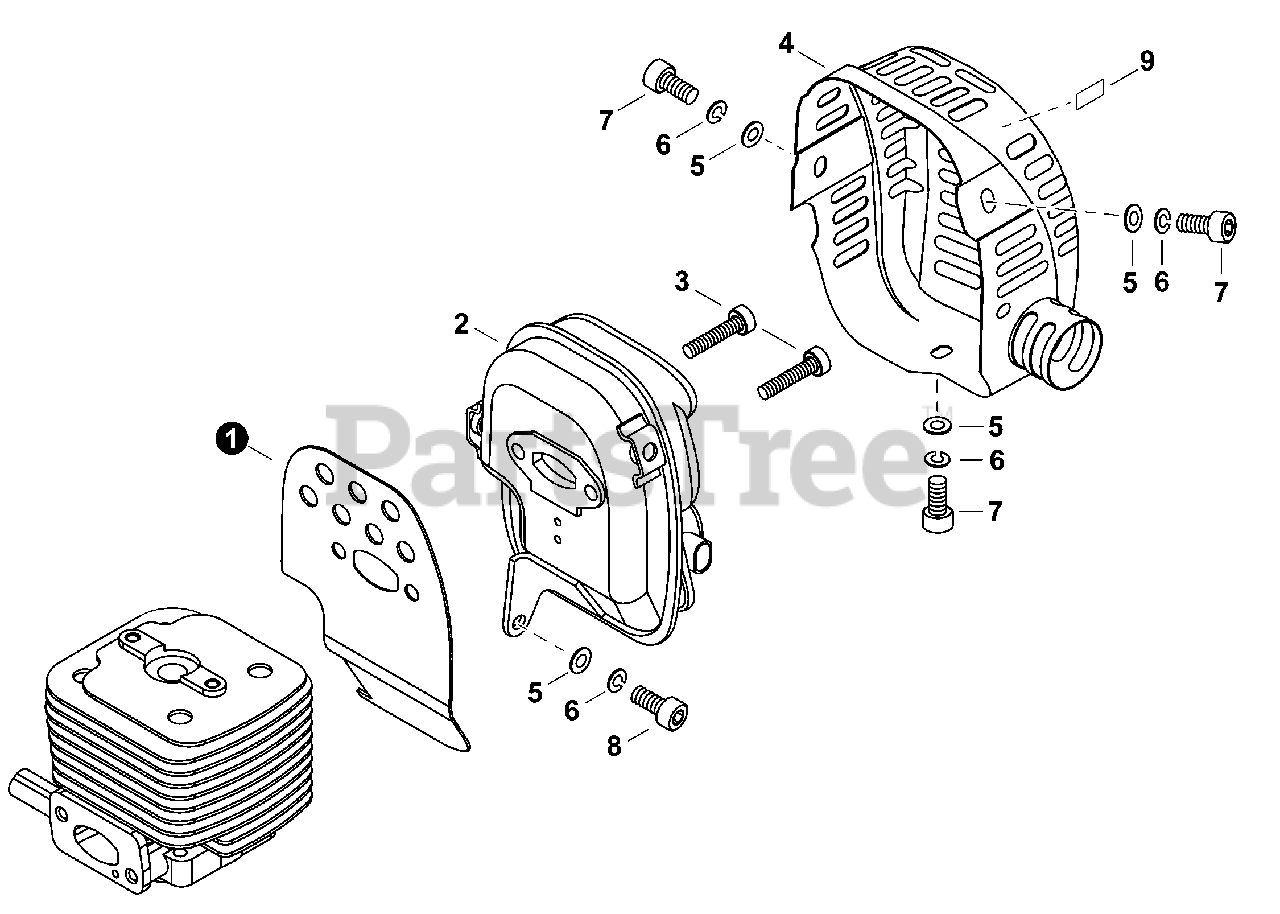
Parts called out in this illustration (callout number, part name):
1	HEAT SHIELD, EXHAUST
2	MUFFLER
3	BOLT 6
4	COVER, MUFFLER
5	WASHER 5.5x12x0.8
6	WASHER, SPRING 5
7	BOLT 5x10
8	BOLT 5
9	LABEL - CAUTION - HOT
